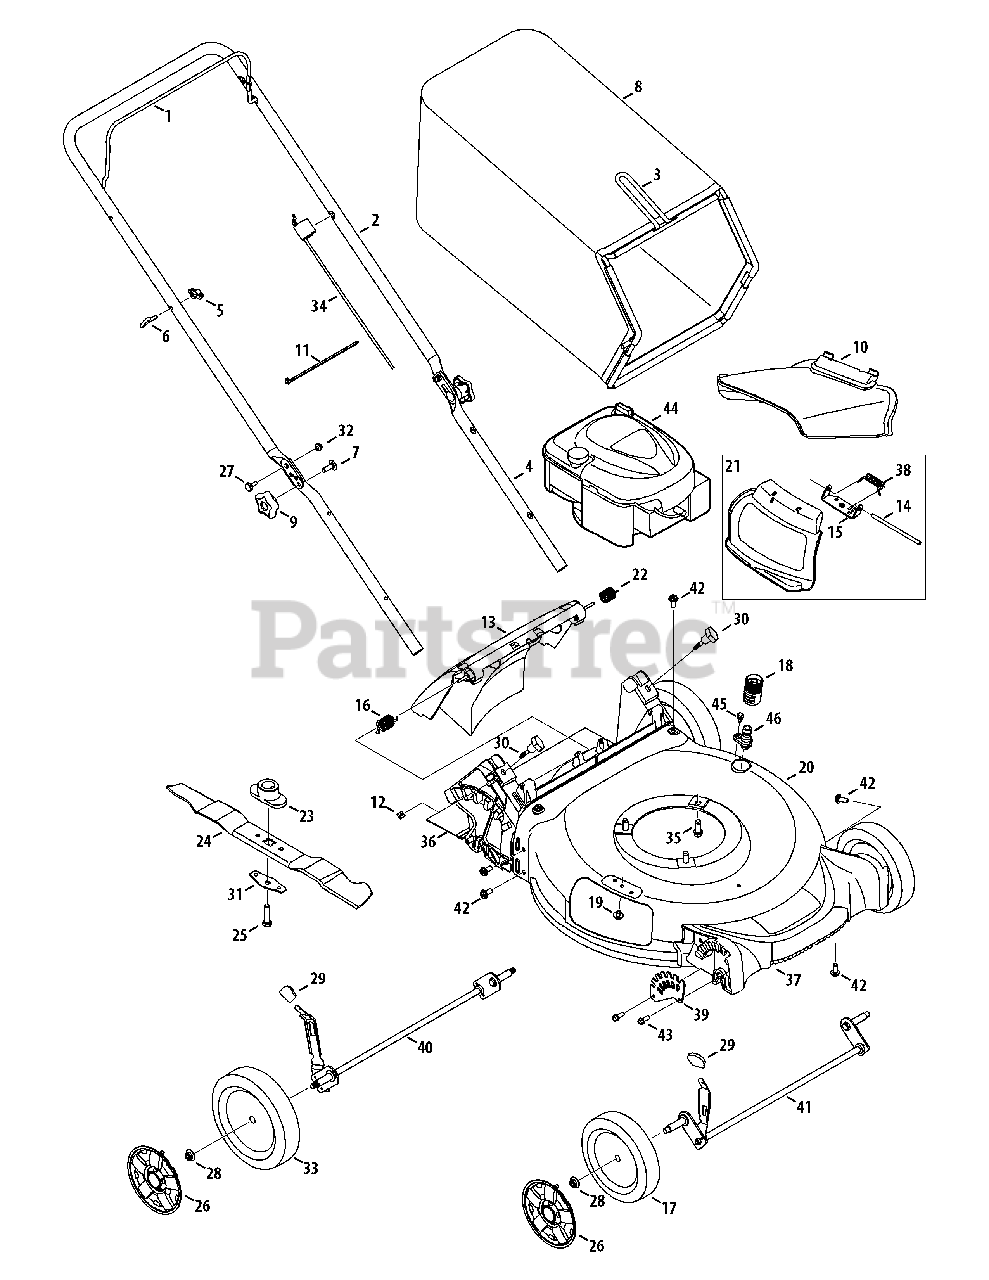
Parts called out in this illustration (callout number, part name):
1	Blade Control
2	Upper Handle
4	Lower Handle
5	Wing Nut
6	Rope Guide
7	Carriage Screw, 5/16-18
8	Grass Bag
9	Hand Knob
10	Side Chute
11	Cable Tie
12	Nut, Sq., 1/4-20
13	Rear Discharge Door Assembly
14	Hinge Pin
15	Chute Deflector Bracket
16	Torsion Spring - RH
17	Wheel, 7 x 2
18	Water Nozzle Adapter
19	Screw, 1/4-20 x .500
20	Deck - 21"
21	Hinged Mulch Plug Assembly
22	Torsion Spring - LH
23	Blade Adapter
24	Mulching Blade
25	Screw , 3/8-24 x 1.50
26	Hub Cap - Front
26	Hub Cap - Rear
27	Sldr. Screw, .375 x .126 x 1/4-20
28	Flange Lock Nut, 3/8-16
29	Adjustment Lever Knob
30	Wing Nut
31	Blade Bell Support
32	Nut, Flange Lock, 1/4-20
33	Wheel, 8 x 2
34	Control Cable
35	TT Screw, 3/8-16 x 1.0
36	Trail shield
37	Front Cover
38	Torsion Spring
39	Front Height Adjuster Plate
40	Rear Axle Assembly
41	Front Axle Assembly
42	Screw, 5/16-14 x .750
43	Screw, 1/4-15 x .750
44	Engine - 126M02-6863-F1
45	Screw, 1/4-20 x .500
46	Deck Wash Nozzle
